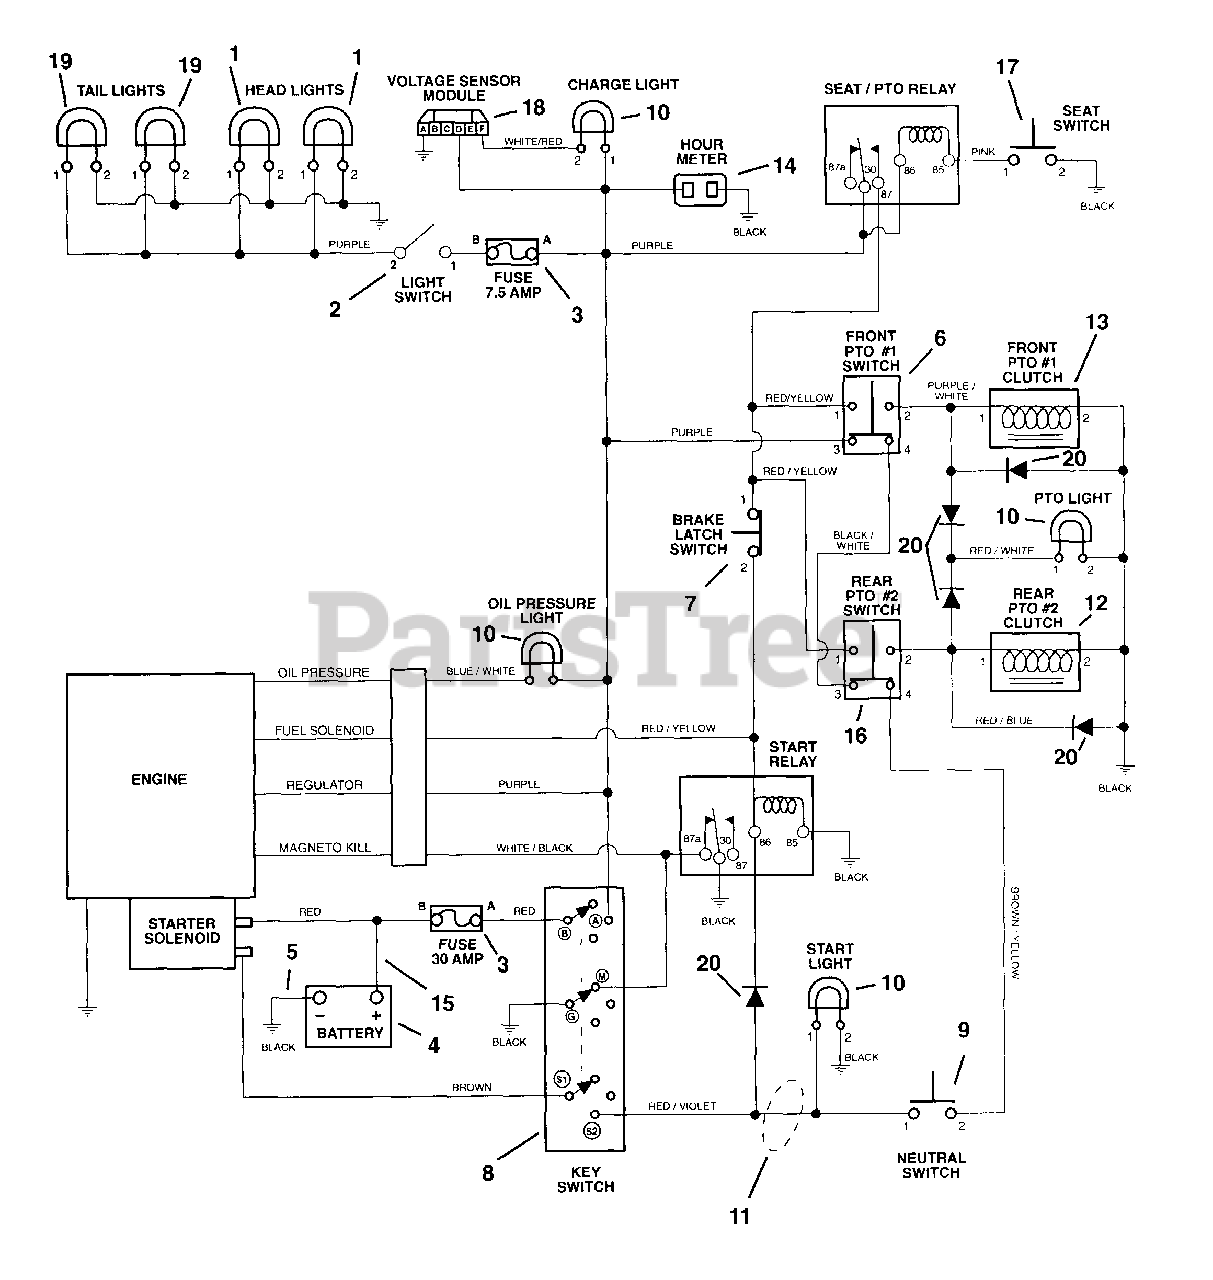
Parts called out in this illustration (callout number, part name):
1	Headlights-Right Hand
1	Headlights-Left Hand
2	Switch-Light
4	Battery
5	Cable-Negative Battery
6	PTO Knob/Switch Assembly
7	Switch N.C.
8	Key Switch
9	Switch-Single Pole N.O.
11	Wire Harness
12	Electric Clutch
13	Clutch-Electric-Warner
14	Hour Meter
15	Cable-Battery to Solenoid
16	Clutch Switch
17	Switch-Seat
18	Module-Voltage Sensor
19	Tail Light Assembly
20	Molded Diode Plug-Clear Lamp
